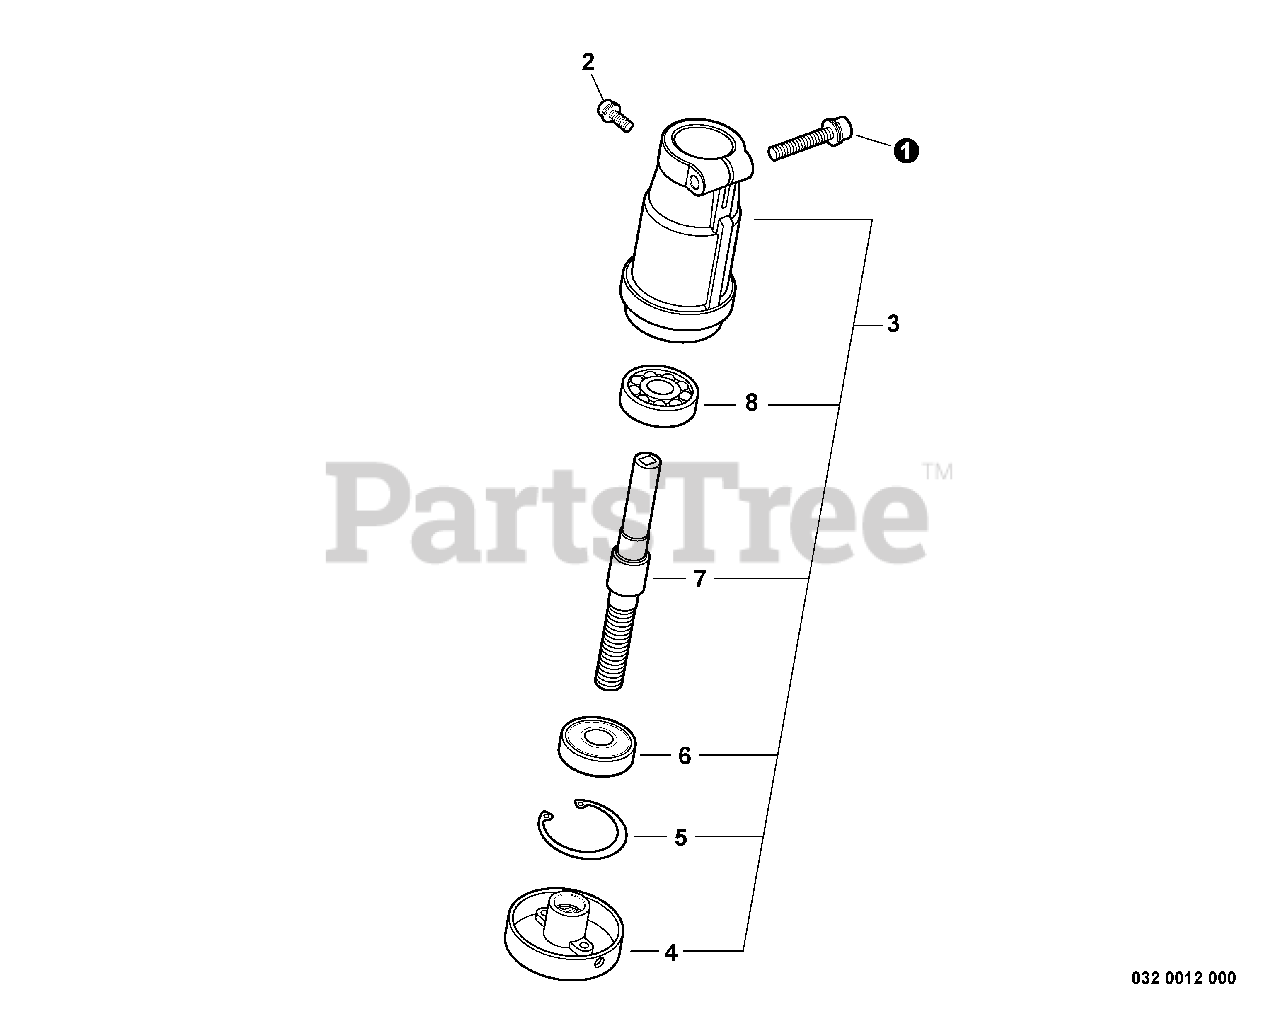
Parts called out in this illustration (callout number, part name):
1	SCREW - 5X25
2	SCREW - 4X10
3	GEAR CASE ASSY
4	ADAPTOR, BLADE - UPPER
5	RING, RETAINING - 30
6	BEARING, BALL - 6200
7	GEAR - SHAFT
8	BEARING, BALL - 6200
